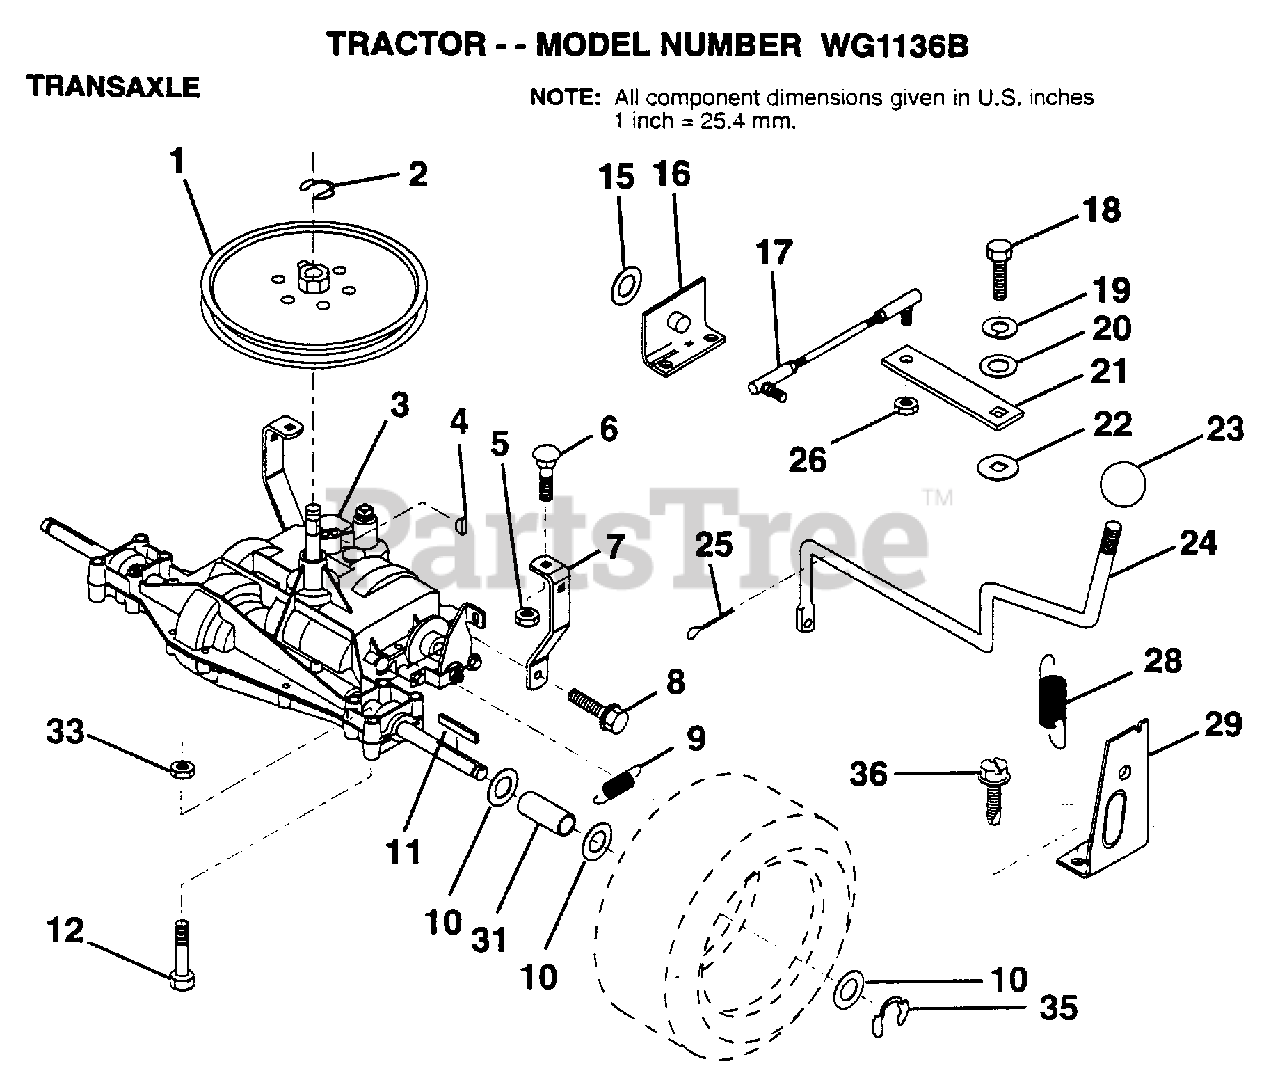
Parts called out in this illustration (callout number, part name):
1	PULLEY
6	BOLT
7	"STRAP,TORQUE"
8	SCREW
9	SPRING.BRAKE.RETU
10	WASHER
11	SQUARE KEY
12	BOLT
16	"SUPT,HDLE SHT LH"
17	"LINK,SHIFT"
18	BOLT.1/4-28.W/PAT
19	LOCKWASHER
20	WASHER LT
21	ARM SHIFT
22	WASH-SHFT PLT LT
23	KNOB T (1/2-HOLE)
24	"ROD,SHIFT"
25	PIN COTTER 1/8
26	NUT.LOCK.5/16-24
28	"SPRING,EXT"
29	"SUPT,HDLE RH"
31	SPACER LT
35	E-RING LT
36	SCREW
